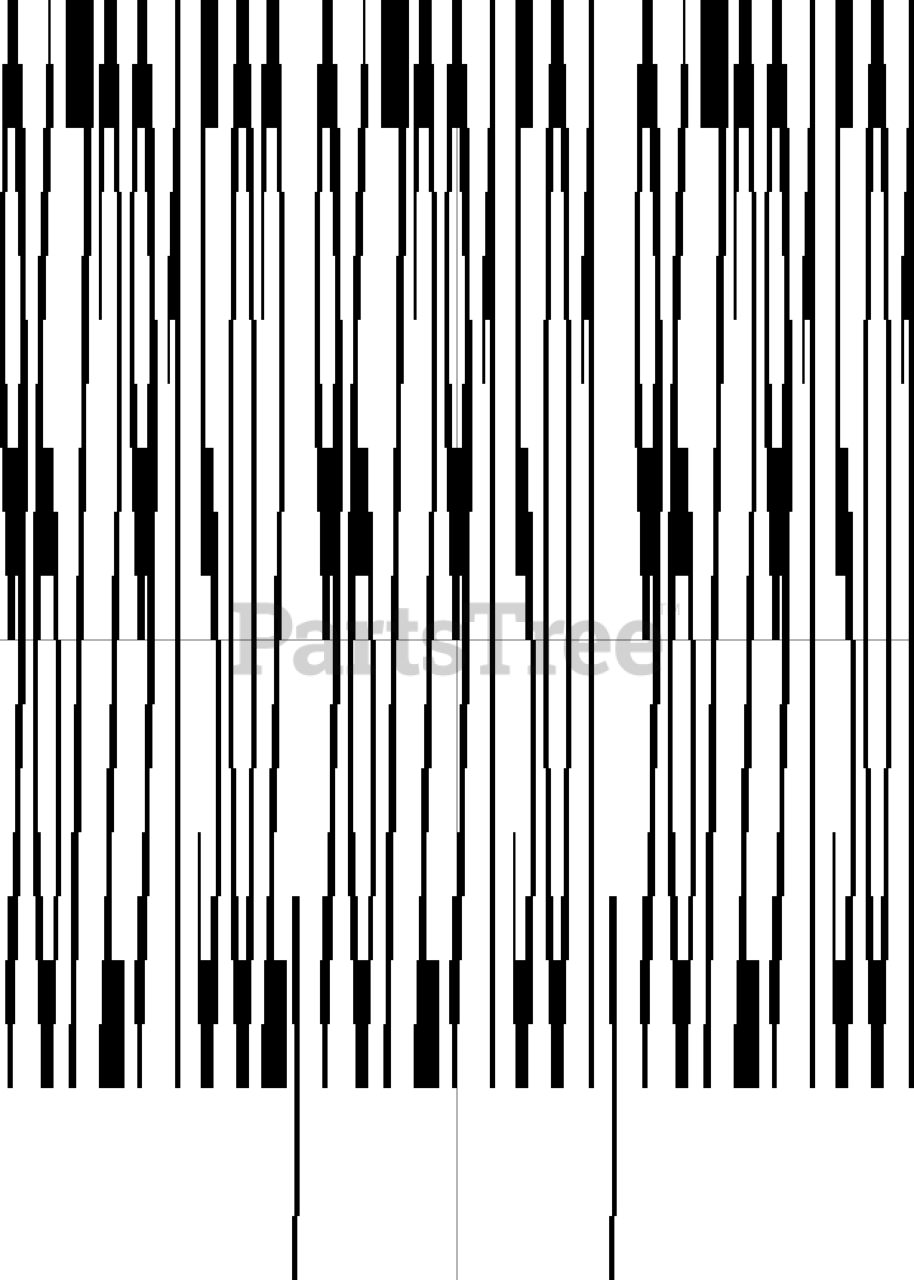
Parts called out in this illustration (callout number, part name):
2	SPRING BRACKET
5	STEERING WHEEL
7	NUT
9	SPACER
10	NUT
11	BRACKET STEERING ASSY WITH BUS
12	BRACKET STEERING ROD ASSY
13	RETAINING RING SGA 15
16	PROTECTIVE COVER
20	COLLAR SCREW
22	WIRE ASSY
25	RETAINING RING
26	STEERING CHAIN
28	WIRE GUIDE
31	Ball Bearing 6005-2rs
32	BALL BEARING 6010 2RS1
33	CIRCLIP SGH 47
34	RETAINING RING SGA 25
